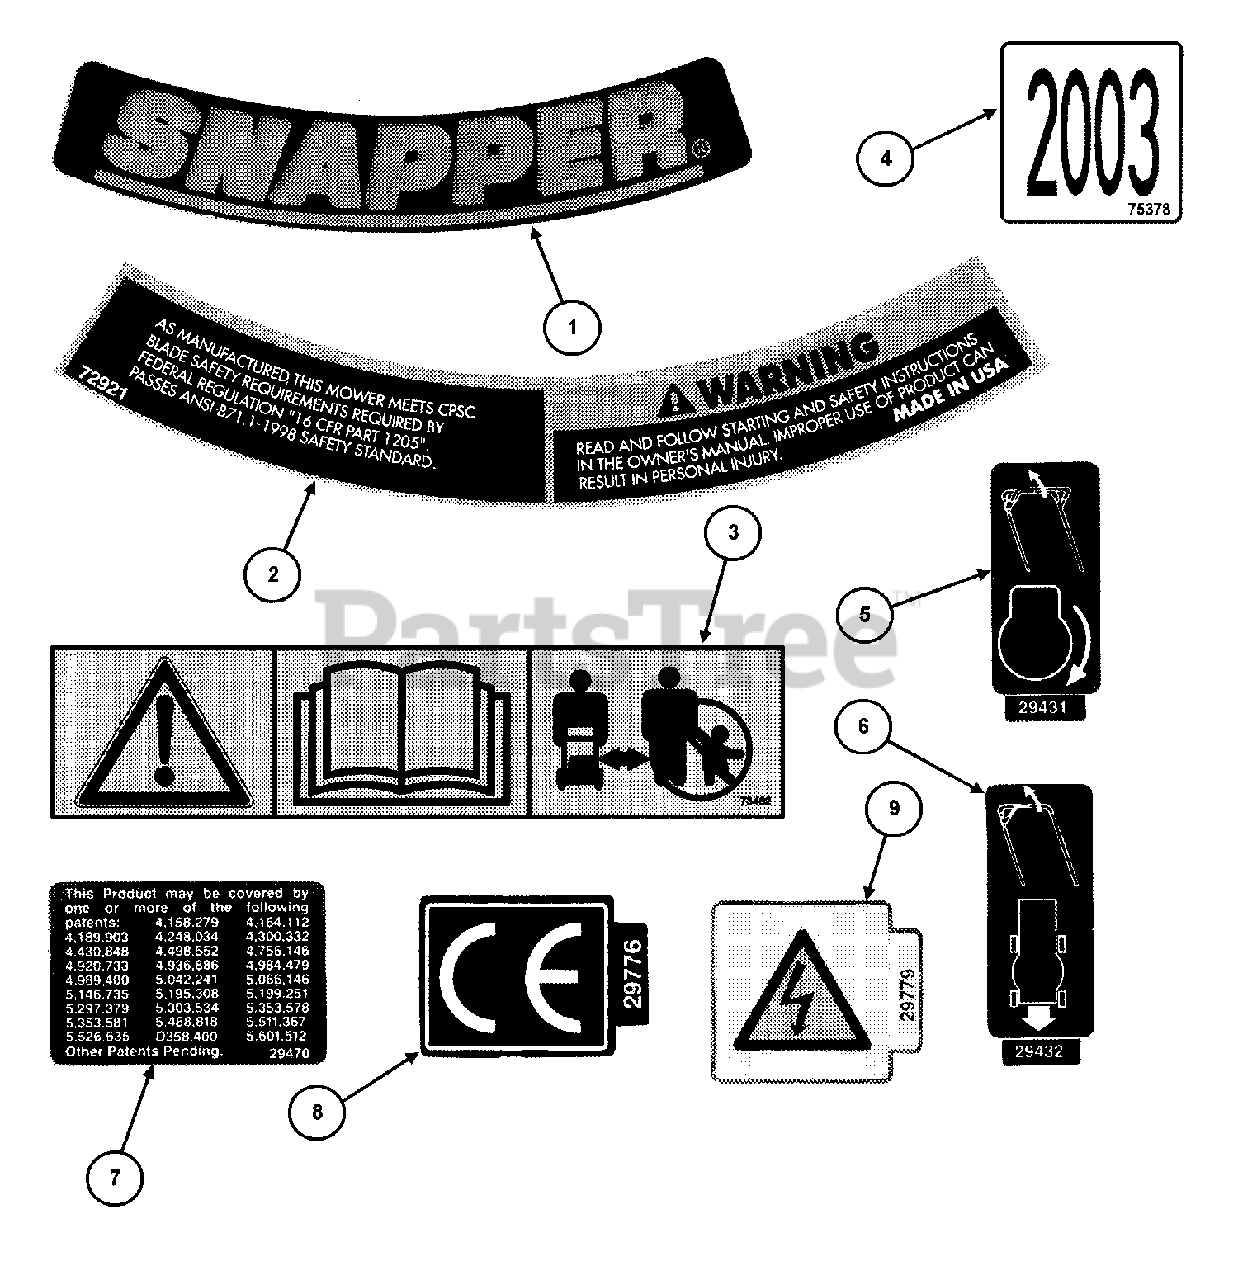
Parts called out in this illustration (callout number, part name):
1	DECAL, SNAPPER, Curved
2	DECAL, Warning (Deck)
3	DECAL, Caution Symbols
4	DECAL, 2002 Year of Manufacture
5	DECAL, Operator Presence Control
6	DECAL, Ground Drive
7	DECAL, Patent Numbers
8	DECAL, European Community (CE)
9	DECAL, Spark Plug International Symbol
